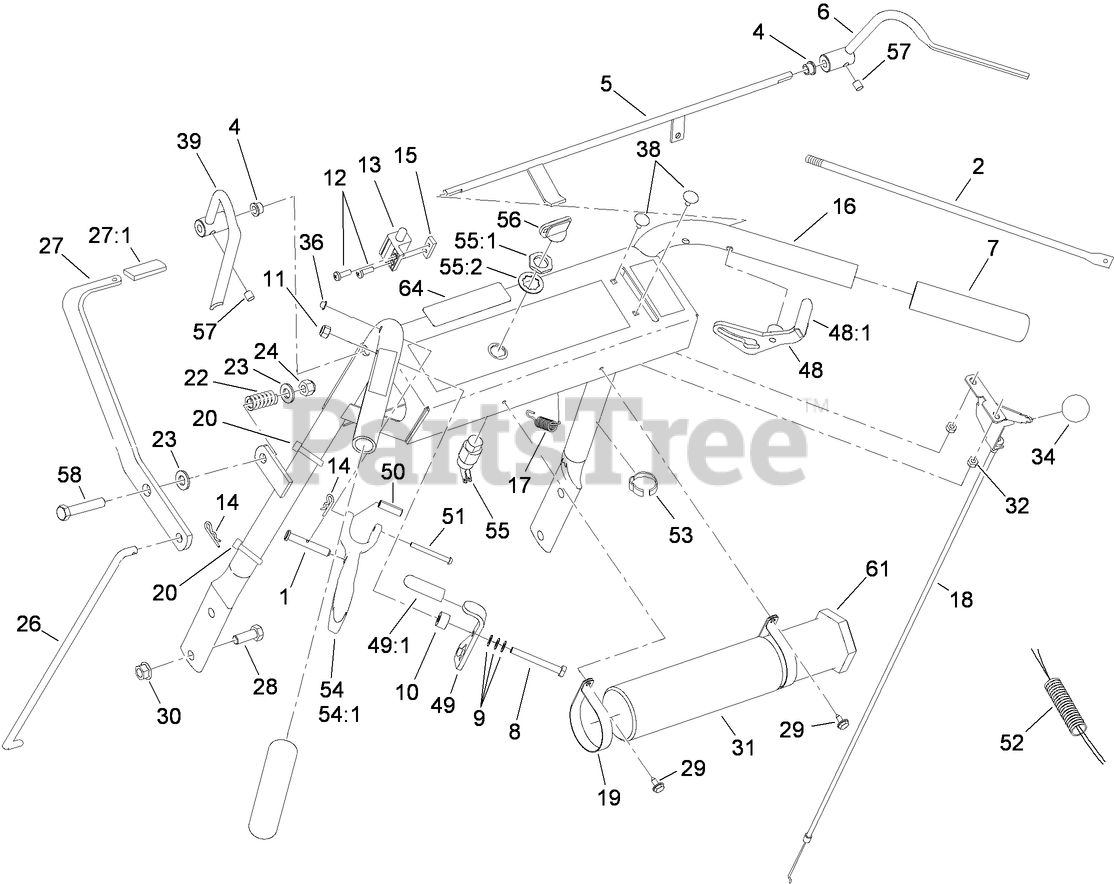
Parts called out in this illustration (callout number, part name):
1	PIN-CLEVIS
2	Linkage-Wheel, Drive
4	BUSHING-NYLON
5	ROD-CONTROL, OPERATOR PRESENCE
6	RH OPERATOR PRESENCE CONTROL LEVER ASM
7	GRIP-FOAM
8	SCREW-HH
9	WASHER-SPRING
10	SPACER
11	NUT-LOCK, NI
12	SCREW-PPH
13	SWITCH-OPEN, NORMALLY
14	PIN-COTTER
15	PLATE-TAPPED
16	HANDLE ASM
17	SPRING-EXTENSION
18	THROTTLE CABLE ASM
19	CLAMP-R
20	TIE-CABLE
22	SPRING-COMPRESSION
23	WASHER-FLAT
24	NUT-LOCK, NI
26	Linkage-Blade, Upper
27	LEVER ASM
27:1	GRIP-LEVER
28	SCREW-HHF
29	SCREW-HWHTF
30	NUT-HF
31	TUBE-MANUAL
32	NUT-LOCK, NI
34	KNOB-BALL
38	BOLT-CARR
39	LH OPERATOR PRESENCE CONTROL LEVER ASM
48	RH THUMB LATCH ASM
48:1	GRIP-LATCH
49	LH THUMB LATCH ASM
49:1	GRIP-LATCH
50	PIN-ROLL
51	PIN-LEVER, DRIVE
52	HARNESS-WIRING
53	Clip-Cable
54	DRIVE LEVER ASM
54:1	GRIP-LEVER, DRIVE
55	SWITCH-ON / OFF
55:1	NUT-HH
55:2	WASHER-TOOTH, INTERNAL
56	KEY-IGNITION
57	SCREW-SET
58	SCREW-HH
61	CAP-HOUSING
64	DECAL-ARRESTER, SPARK
